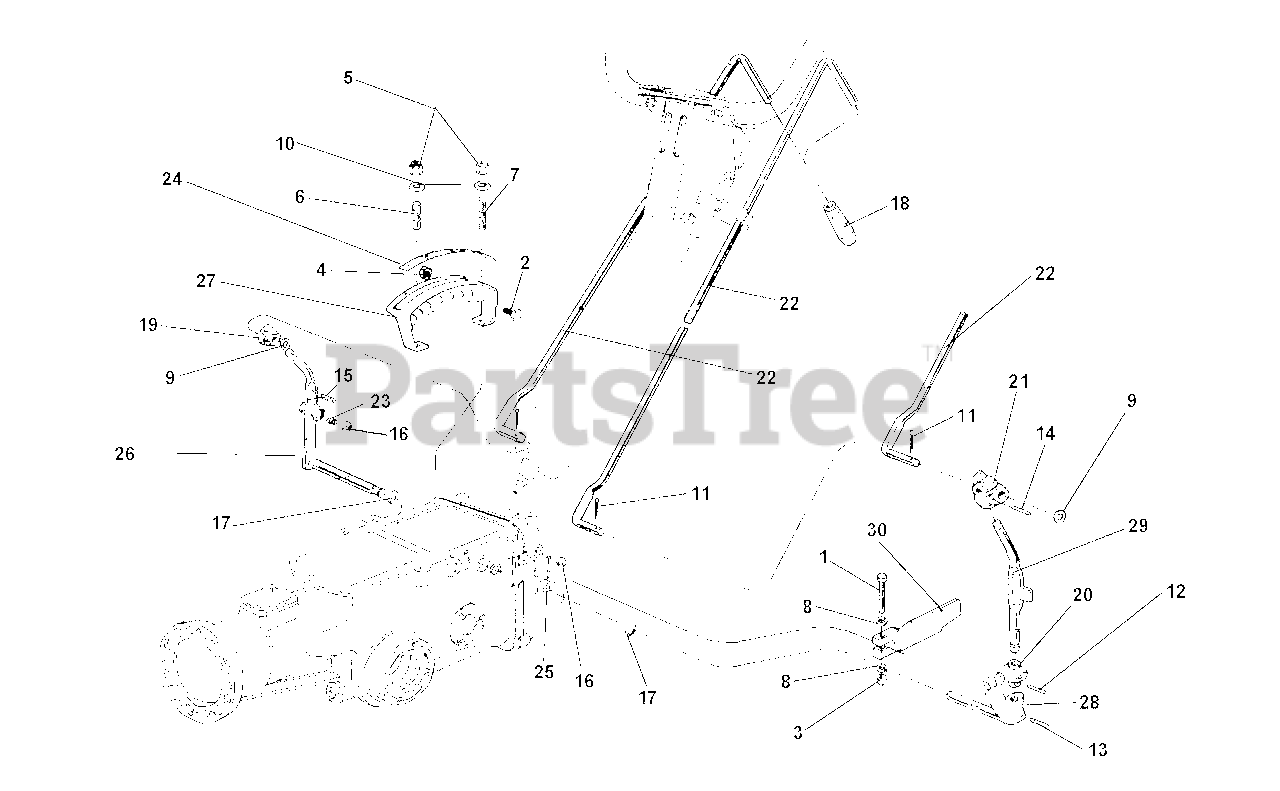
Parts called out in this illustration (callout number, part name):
1	SCREW M6 X 40
2	SCREW M8 X 14
3	NUT, SELF LOCKING M6
4	NUT, SELF LOCKING M8
6	STUD M8 X 38 X 14 X 20
7	STUD M8 X 46 X 16 X 16
8	FLAT WASHER 6.4
9	WASHER P10.5 X 18
10	SUPER WASHER 8 DIN 6796
12	LOCKING PIN 4 X 20 SPIRAL
14	LOCKING PIN 4 X 24 SPIRAL
15	LOCKING PIN SPIRAL
16	BALL 15/32 RIV RB-11.906
17	O-RING 115 11.91 X 2.62
19	JOINT, 715, 725, 735
20	PTO STOP RING
21	PTO ARTICULATION
22	ROD, CONTROL, POWER TILLER
24	SPEED DECAL, 725, 735, 745
26	GEARBOX LEVER
27	SPEED QUADRANT, 725, 735, 745
28	PTO CONTROL PIN, 715, 725, 735
29	PTO CONTROL LEVER
30	PTO LOCKOUT, 725, 735
